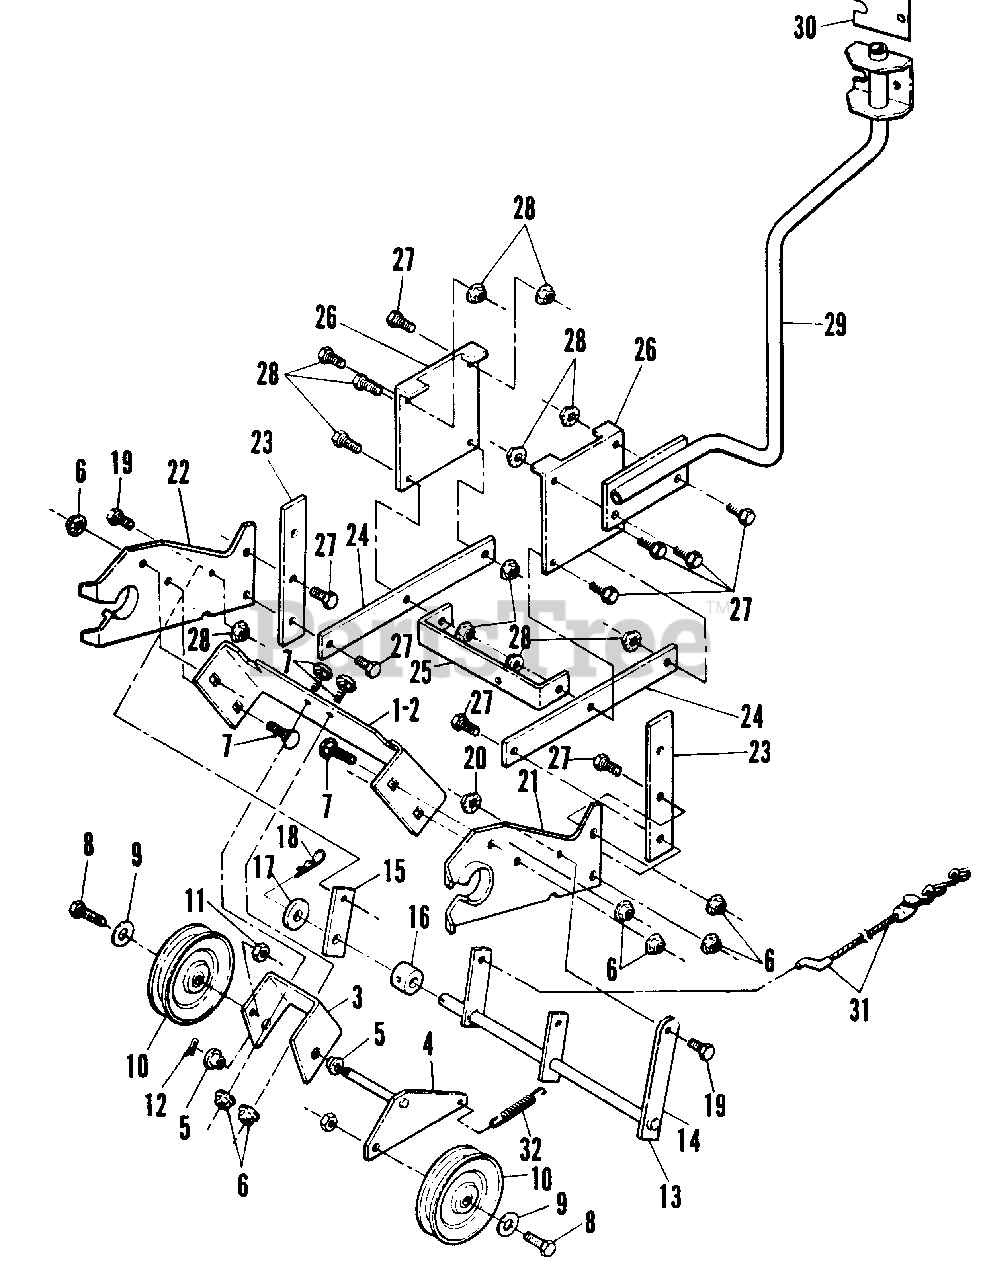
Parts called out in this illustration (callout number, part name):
1	IDLER ASSEMBLY
2	HITCH BRACE
3	IDLER SUPPORT
4	IDLER ARM STR.
5	BEARING
6	NUT, 3/8 - 16 Flange Lock
7	BOLT, 3/8 - 16 x 3/4 Short Neck Carriage
8	BOLT, 3/8 - 16 x 1 1/2 Hex Head Cap
9	WASHER, 3/8
10	IDLER
11	NUT, 3/8 - 16 Hex Cap Lock
12	PIN, 1/8 x 1 Cotter
13	CLUTCH PIVOT ASSEMBLY
14	STRUCTURE, Clutch Engagement
15	PLATE, Fastening
16	SPACER
17	WASHER, Flat
18	COTTER PIN
19	SCREW, 5/16 - 18 x 3/4 Hex Head Cap
20	NUT, 5/16 - 18 Flange Lock
21	HITCH, L.H.
22	HITCH, R.H.
23	HANGER BAR
24	SIDE TIE BAR
25	CROSS BRACE
26	HANGER PLATE
27	BOLT, 3/8 - 16 x 1 Hex Flange Lock
28	NUT, 3/8 - 16 Hex Flange Lock
29	BRACE, Chute Crank
30	DECAL, Chute Control
31	CABLE, PTO (Assembly)
32	SPRING, 6.5"
